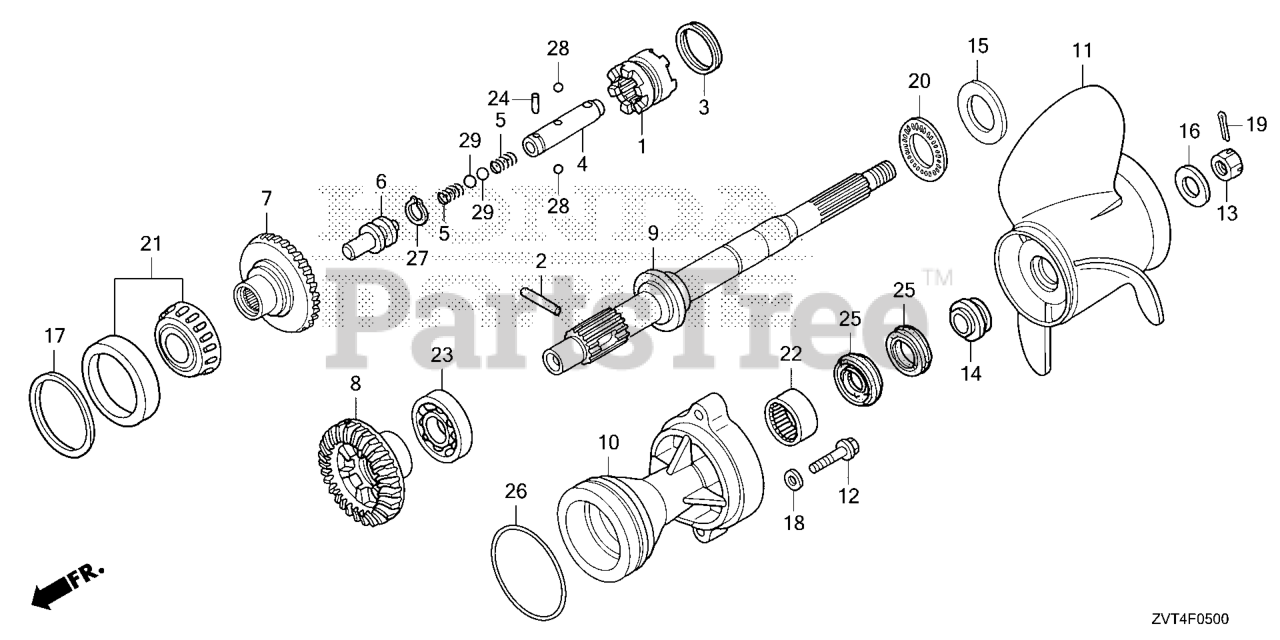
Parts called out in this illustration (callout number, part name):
1	SHIFTER, CLUTCH
2	PIN, SHIFTER (8X47)
3	RING, CROSS PIN
4	SLIDER, SHIFT
5	SPRING, SHIFT
6	PLATE, SHIFT
7	GEAR COMP, BEVEL F
8	GEAR, BEVEL (RVS. 30T)
9	SHAFT, PROPELLER
10	HOLDER, PROPELLER SHAFT *NHB14M* (AQUA MARINE SILVER METALLIC)
10	HOLDER,PROP*NH565*
11	PROPELLER, THREE-BLADE (15-1/2X13) *NH283* (AL) (STIN GRAY)
11	PROPELLER, THREE-BLADE (15-1/4X15) *NH283* (AL) (STIN GRAY)
11	PROP (15X17) *NH283*
11	PROPELLER, THREE-BLADE (14-3/4X19) *NH283* (AL) (STIN GRAY)
11	PROPELLER, THREE-BLADE (14-1/2X21) *NH283* (AL) (STIN GRAY)
11	PROPELLER, THREE-BLADE (14-1/4X23) *NH283* (AL) (STIN GRAY)
11	PROPELLER, THREE-BLADE (14-1/2X15) (SUS)
11	PROPELLER, THREE-BLADE (14-1/4X17) (SUS)
11	PROPELLER, THREE-BLADE (14X19) (SUS)
11	PROPELLER, THREE-BLADE (14X21) (SUS)
11	PROPELLER, THREE-BLADE (14-1/2X23) (SUS)
11	PROPELLER, THREE-BLADE (14X25) (SUS)
12	BOLT, FLANGE (10X40)
13	NUT, CASTLE (18MM)
14	WASHER, PROPELLER THRUST
15	WASHER, THRUST BEARING
16	WASHER, PROPELLER
17	SHIM A, BEVEL (0.10)
17	SHIM B, BEVEL (0.15)
17	SHIM C, BEVEL (0.30)
17	SHIM D, BEVEL (0.50)
18	WASHER, PLAIN (10MM)
19	PIN, SPLIT (4.0)
20	BEARING, THRUST (F)
21	BEARING, TAPER (50X90X28)
22	BEARING (30X37X26)
23	BEARING, RADIAL BALL (50X90X20)
24	ROLLER (3X12.8)
25	SEAL, WATER (30X45X7)
26	O-RING (105X3.1)
27	CIRCLIP (OUTER) (14MM)
28	BALL, STEEL (#7) (7/32)
29	BALL, STEEL (#9) (9/32)
